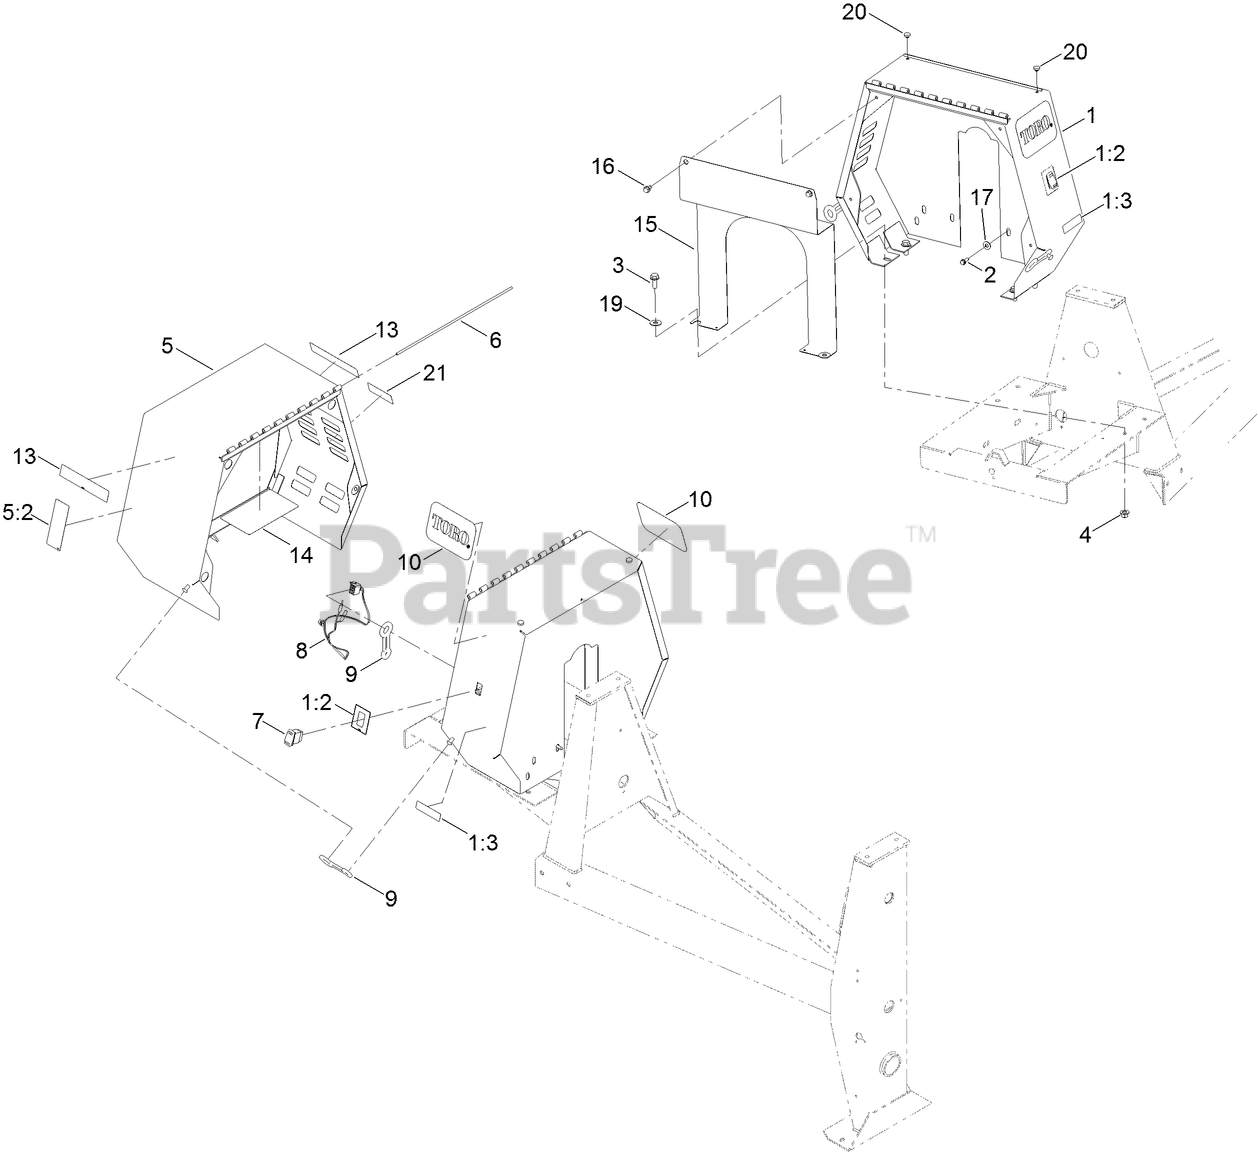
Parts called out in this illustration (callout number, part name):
1	STATIONARY COWL ASM
1:2	DECAL-STOP, ENGINE
1:3	DECAL-ARRESTOR, SPARK
2	SCREW-THD ROLL, HWH
3	SCREW-HHF
4	NUT-LOCK
5	MOVABLE COWL ASM
5:2	DECAL-WARNING
7	SWITCH
8	HARNESS-WIRE, MIXER
9	LATCH-RUBBER
10	DECAL
14	DECAL-SERVICE
15	PLATE-ENGINE
16	SCREW-HWH
17	WASHER-FLAT
19	WASHER-FLAT
20	BUMPER
